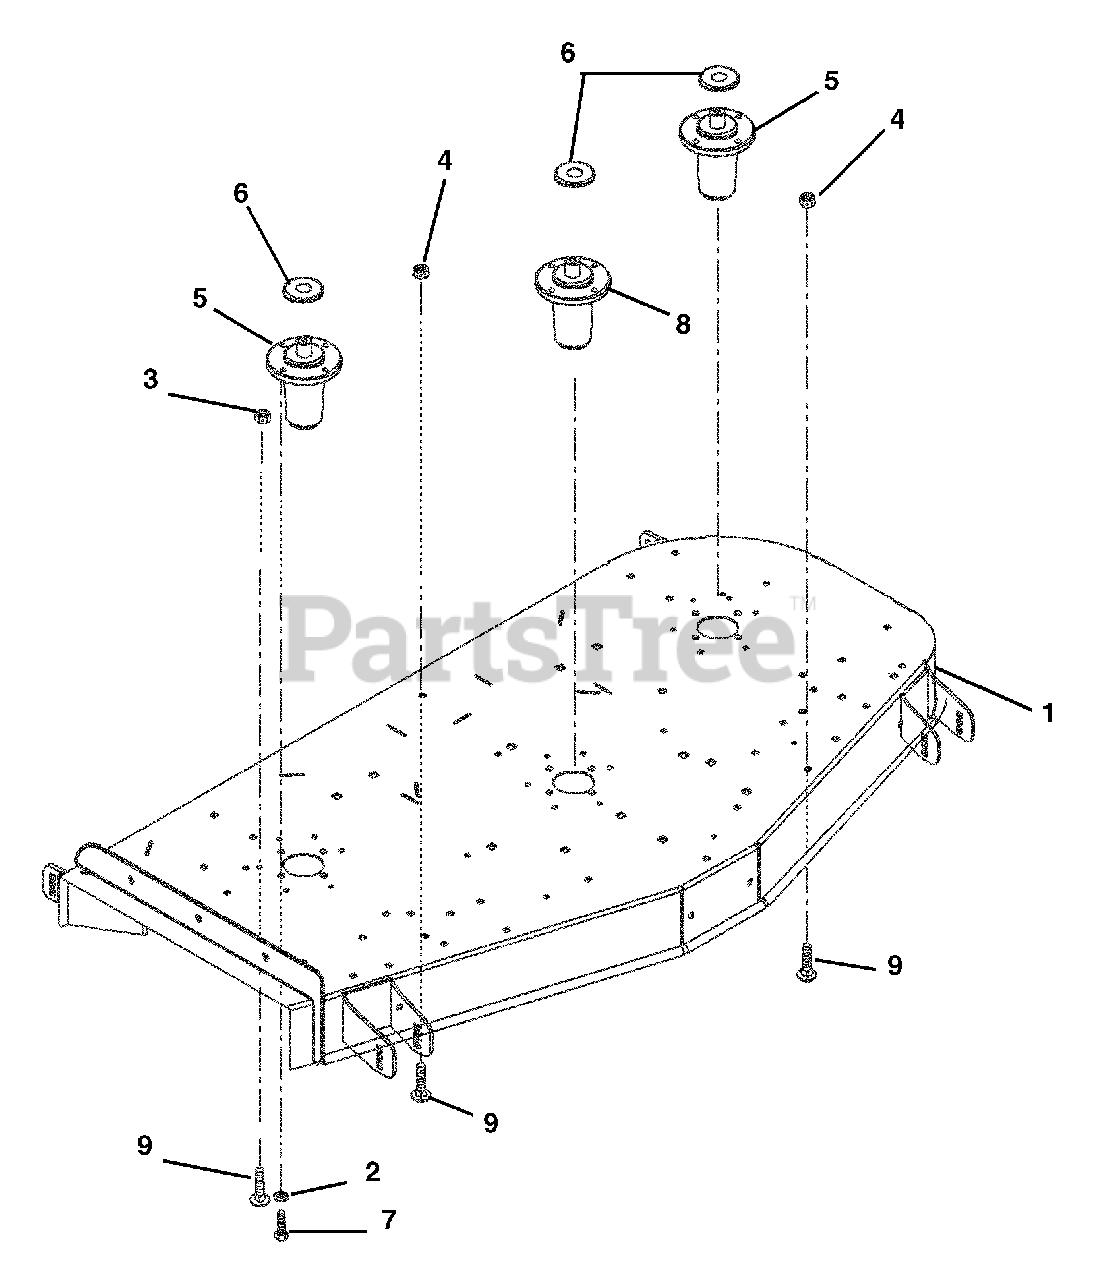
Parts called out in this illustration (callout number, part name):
1	Weldment, 72" Deck (Side Discharge)
2	Washer-Locking .38 x .094
3	Nut-Locking-Center .38-16
4	Nut-Locking-Nylon .38-16
5	Assembly, Spindle L-Hub
6	Slinger-Dust
7	Bolt-Hex .38-16 x 1.25 Grade 5
8	Spindle Assembly (Center)
9	Bolt-Round Head Square Neck .38-16 x 1.00 Grade 5
